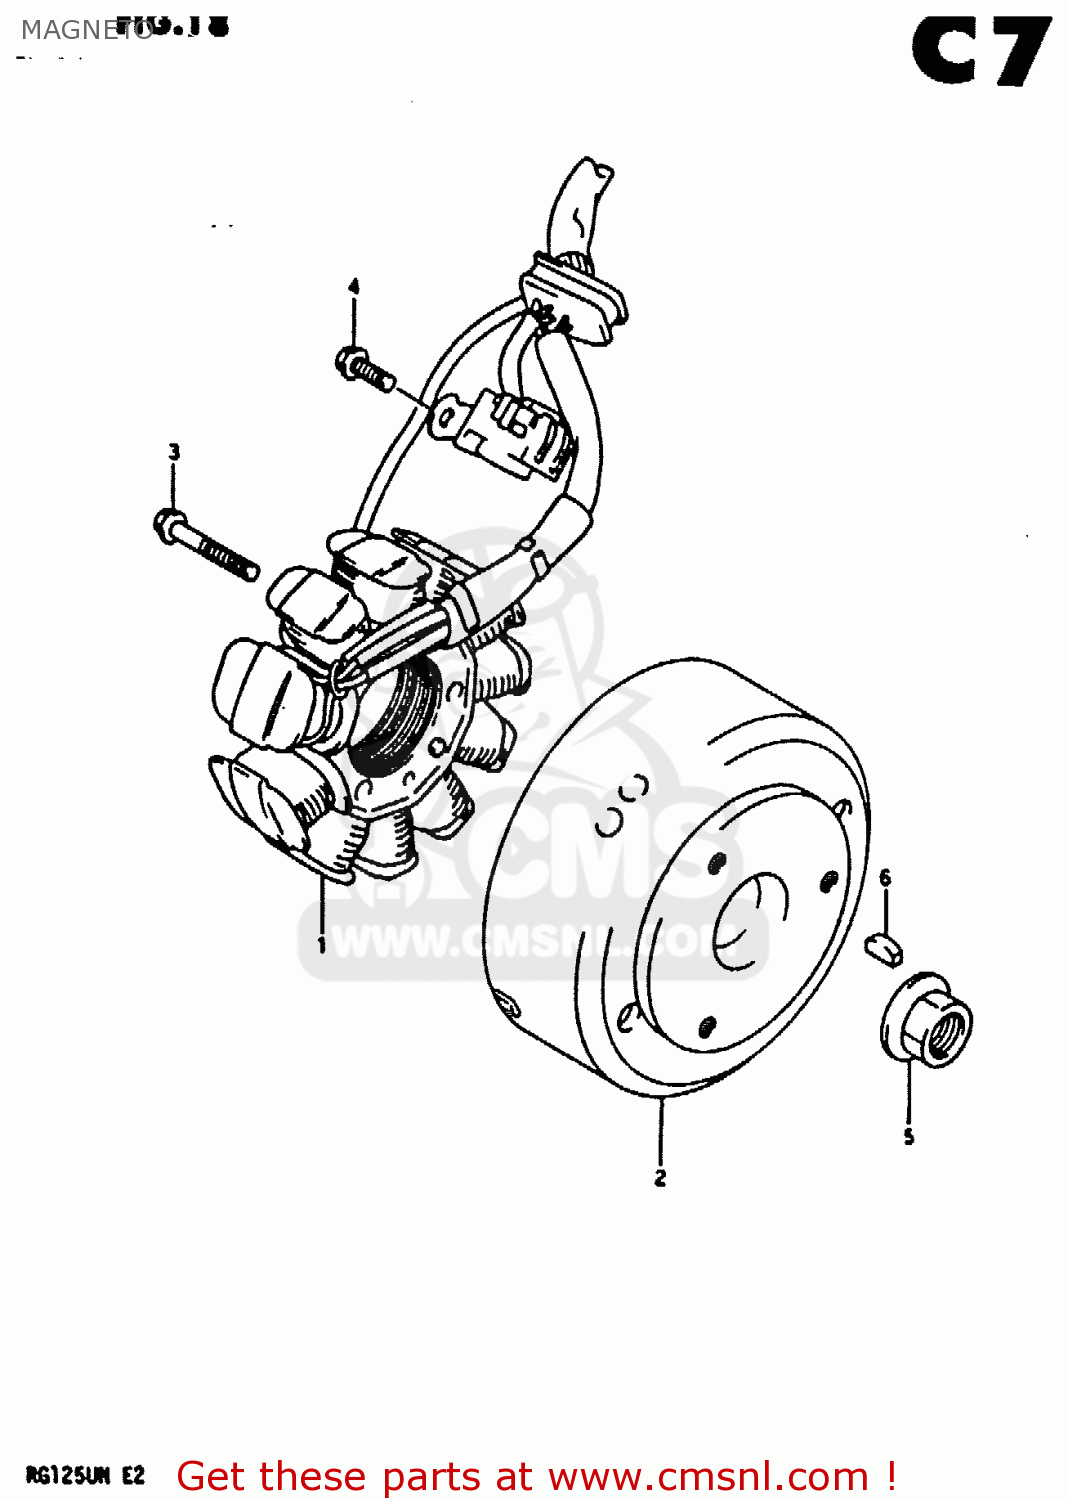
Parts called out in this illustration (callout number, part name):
1	STARTER ASSY
2	ROTOR, FLYWHEEL
3	BOLT
4	BOLT
5	NUT
6	KEY
